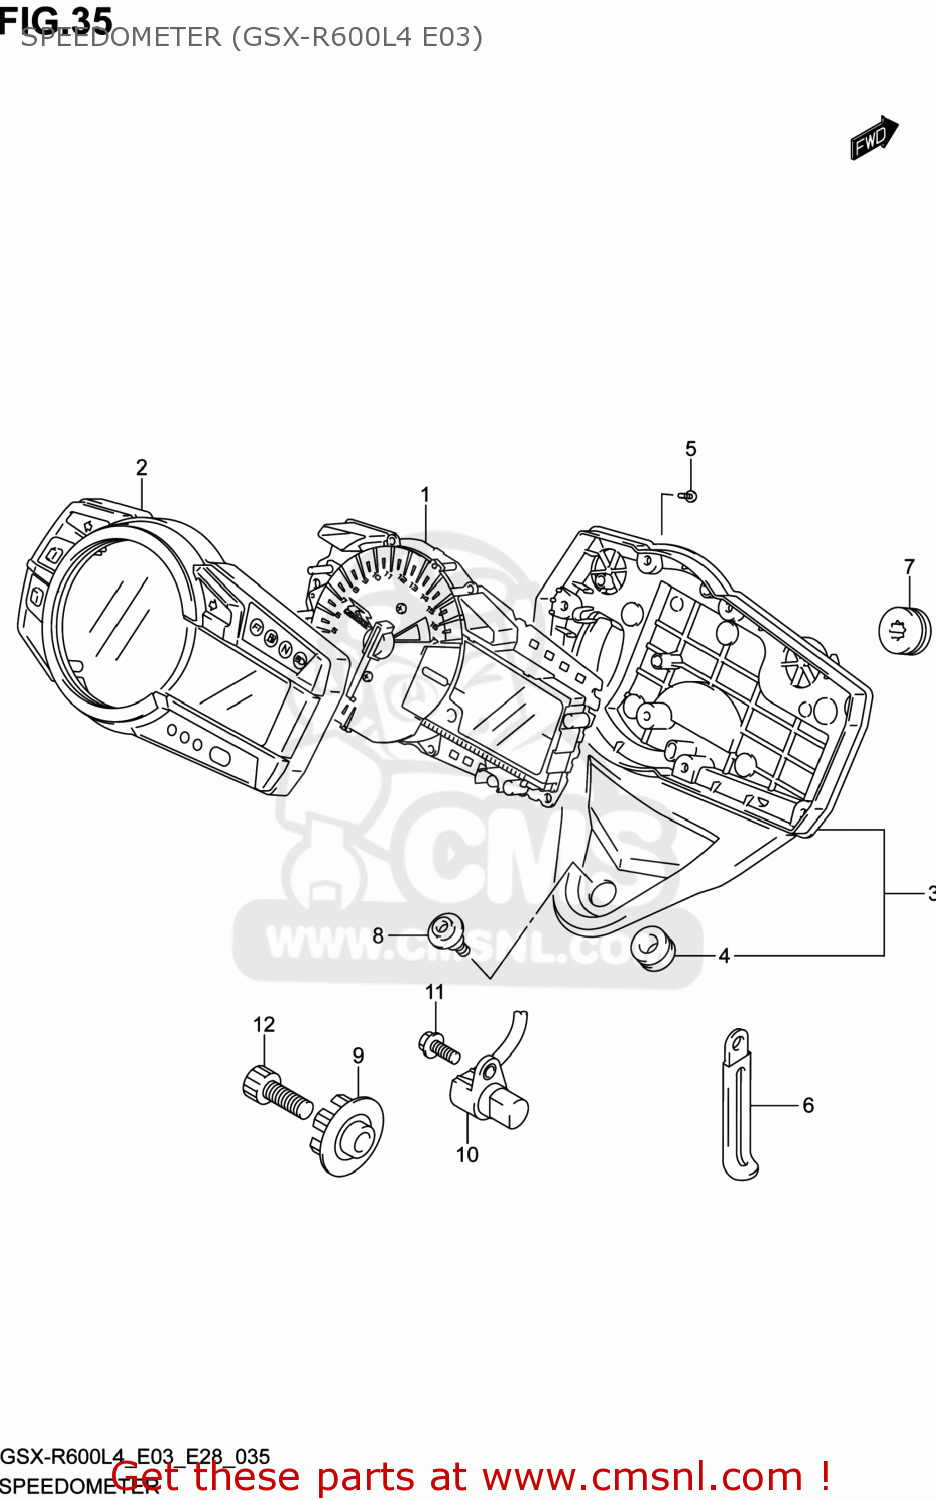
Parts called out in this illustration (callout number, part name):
1	SPEEDOMETER
2	CASE ASSY,UPR
3	LWR CASE ASSY
4	CUSHION,METER
5	SCREW(3X16)
6	CLAMP(L:45)
7	CUSHION
8	SCREW,SPEEDOMETER
9	ROTOR,SPEED
10	SENSOR,SPEED
11	BOLT
12	BOLT
